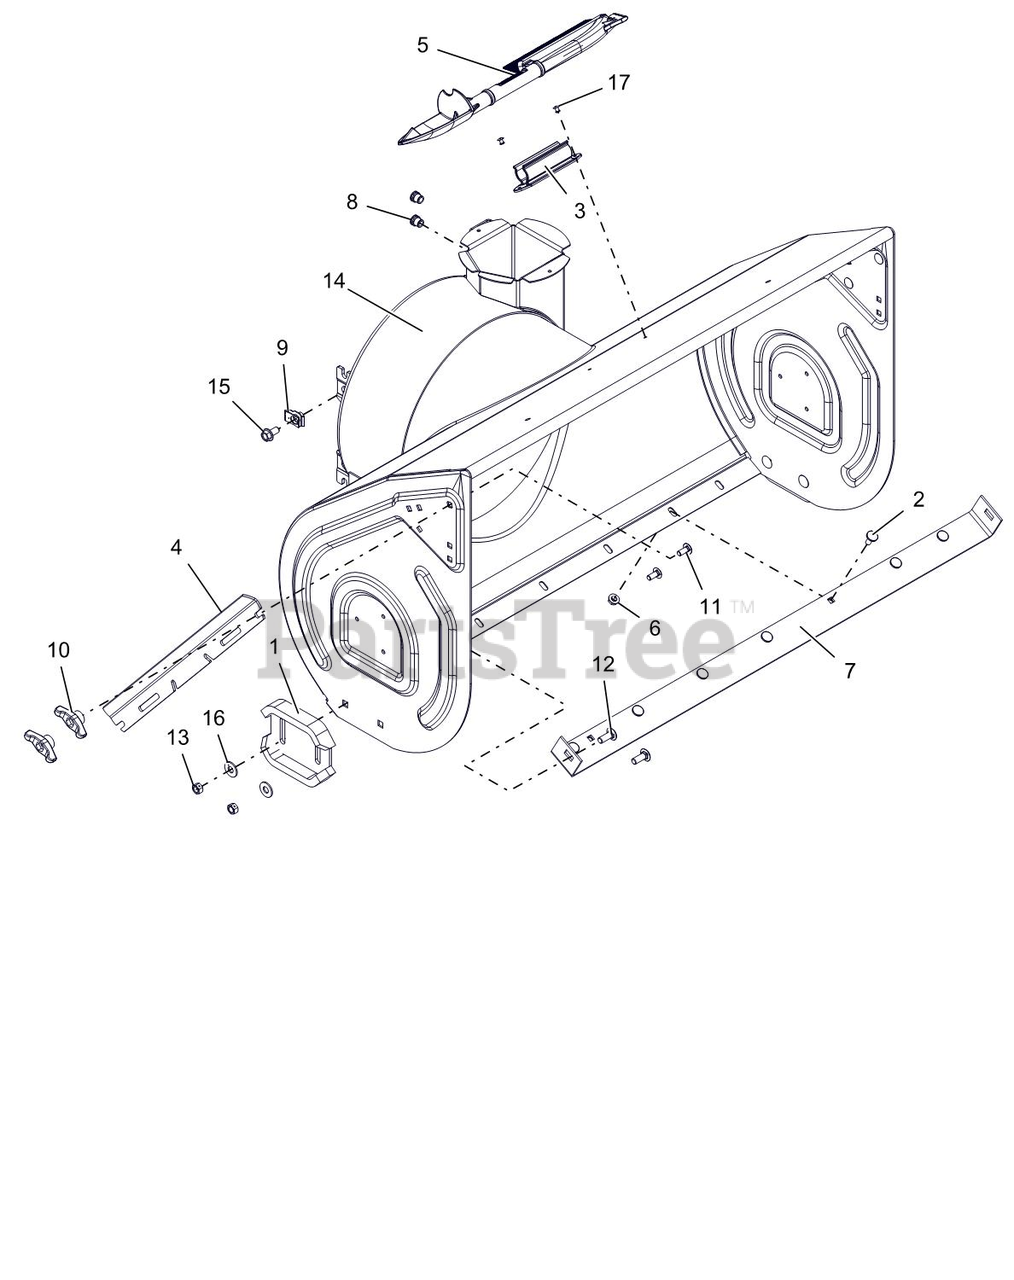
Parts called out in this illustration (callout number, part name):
1	RUNNER, SKID SHOE
2	BOLT, MODIFIED HEAD CARRIAGE
3	MOUNT, SNOW CLEAN OUT
4	CUTTER, DRIFT
5	DEVICE, SNOW CLEAN OUT W/BRUSH
6	@NUT-LK-TOP-FLG .31-18 YWZC
7	BLADE, SCRAPER-36"
8	NUT, THREADED INSERT .38-16
9	NUT-RTNR .375-16X.37
10	KNOB,WING .31-18 UNC NYL/TALC
11	@BLT-RHDSSQNK .31-18X.75 G5YZ
12	@BLT-RDHDSHSQNK.38-16X1.0 G5YZ
13	@NUT-LK-CTR .38-16 YWZC
14	BLOWER HOUSING W/DECAL 36"
15	BLT-SERHFWH .38-16X.75 YWZC
16	@WSHR-FL-STL.438X1.00X.083 YWZ
17	RVT-POP .187 YZ
